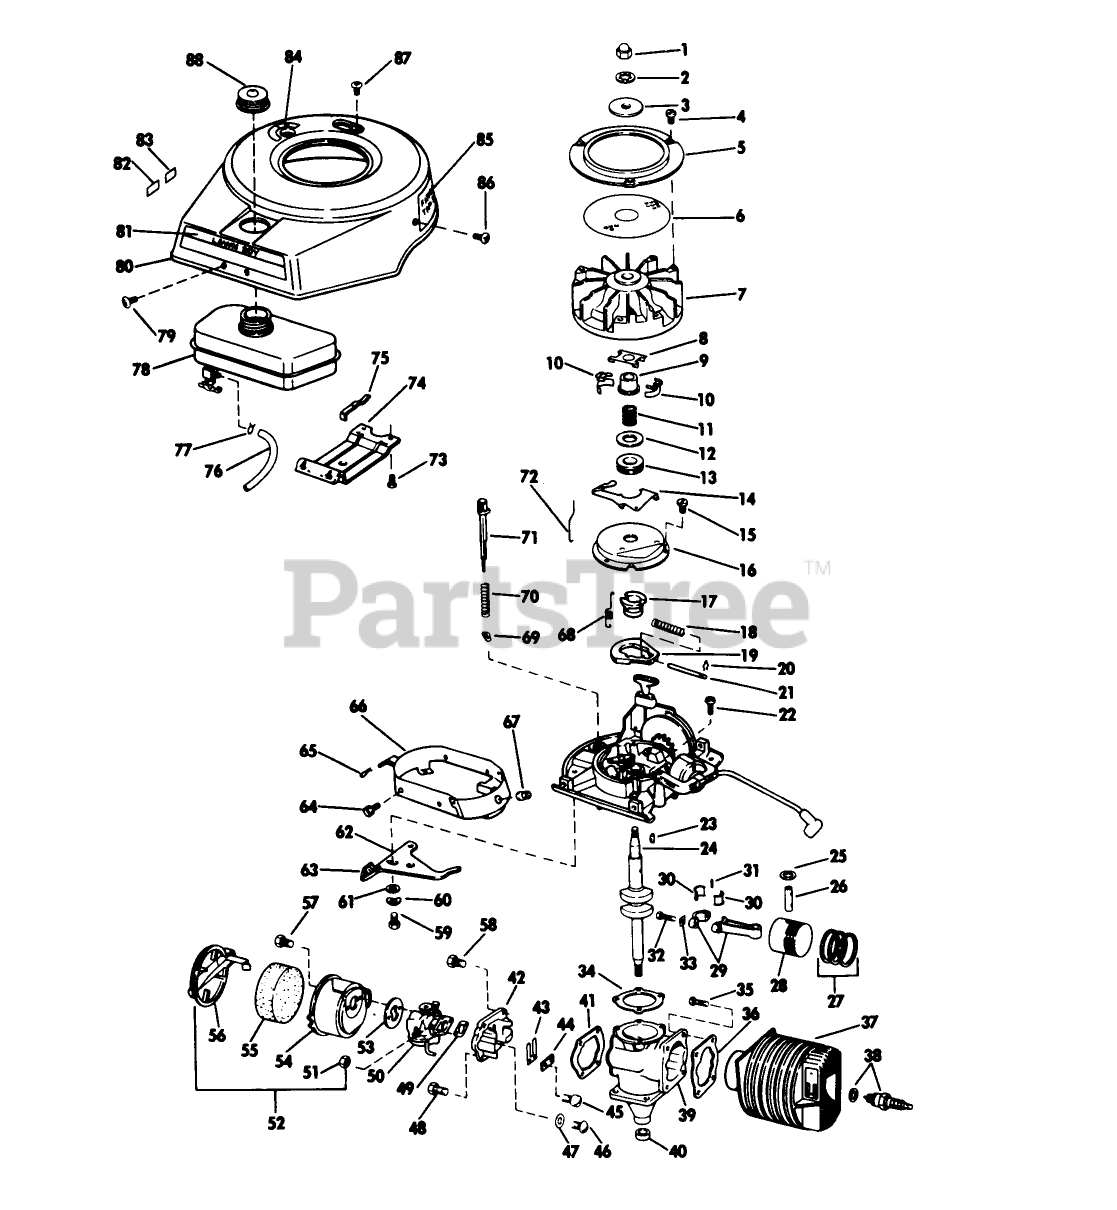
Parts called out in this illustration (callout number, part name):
5	Ring-Flywhl. Scrn.
9	COLLAR S
11	SPRING S
13	THRUST COLLAR S
14	LEVER-GOVERNOR S
15	SCREW S
16	DUST COVER S
17	SPARK ADV. S
18	SPARK ADV. SPRING S
19	FLYWEIGHT S
20	SPARK ADJ. SPRING
21	PIN,SPARK ADV. S
25	RING-RETAINING
30	LINER ASM
34	GASKET S
36	GASKET S
44	PLATE-BACKUP, REED
48	SCREW S
49	GASKET S
51	STOP NUT
55	AIR FIL.ELEM S
57	SCREW S
58	SCREW S
64	SCREW S
67	NUT-CLIP
70	SPRING S
73	SCREW S
76	GAS LINE
77	CLAMP - HOSE S
86	SCREW S
